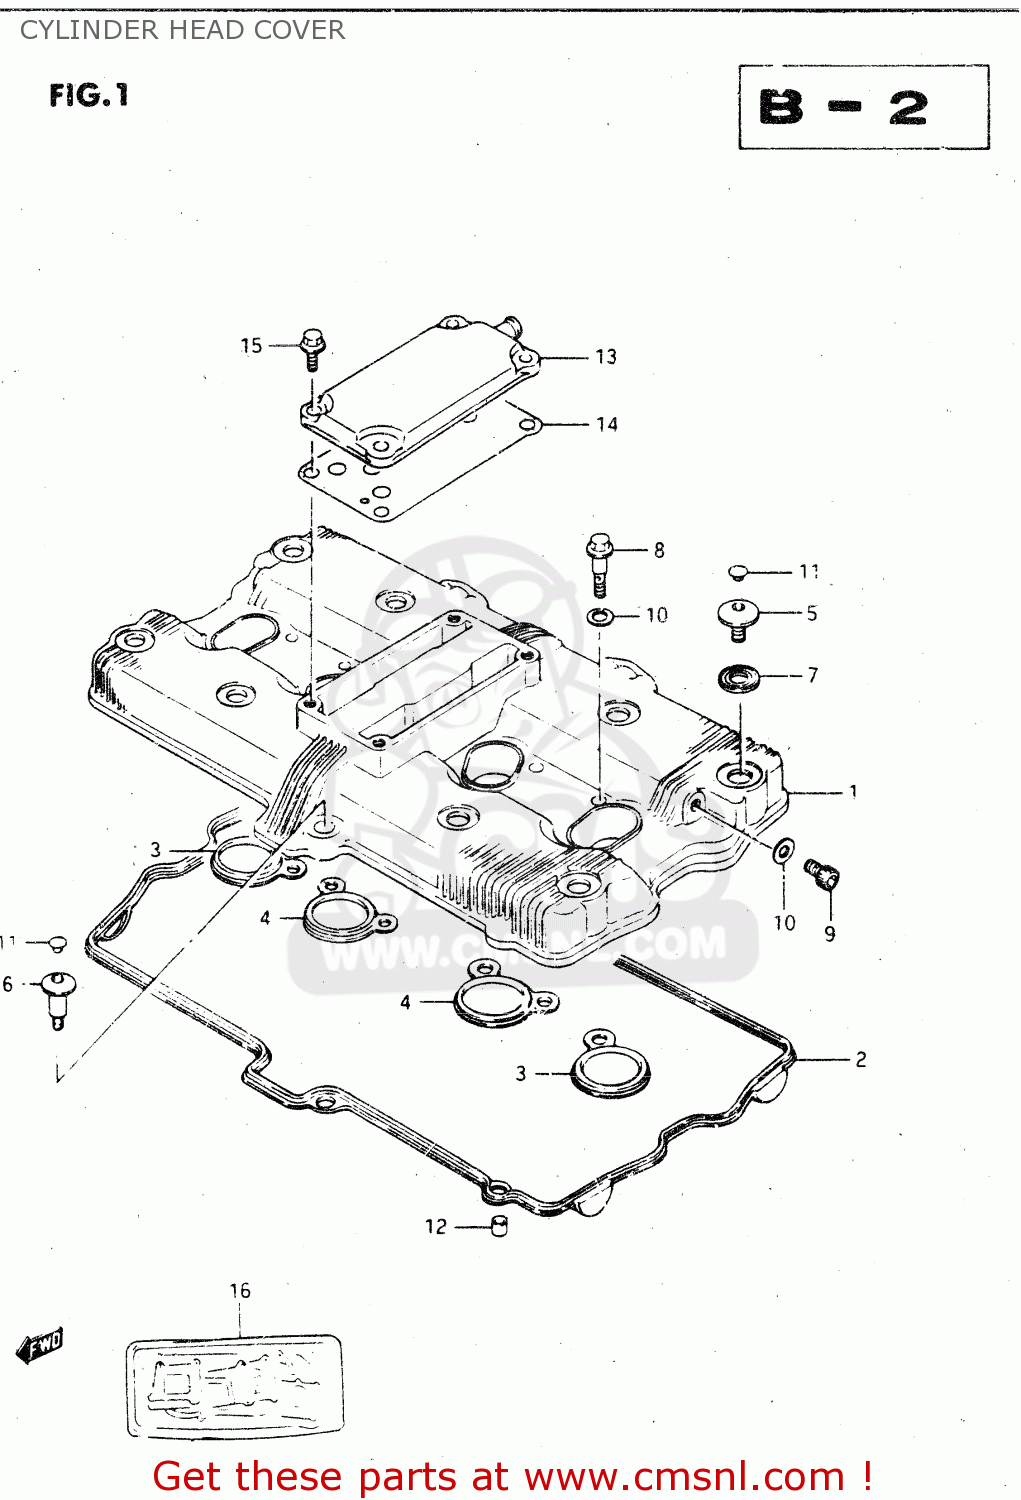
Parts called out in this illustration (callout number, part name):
1	COVER,CYLINDER HEAD
2	GASKET,CYLINDER HEAD COVER (NAS)
3	GASKET (NAS)
4	GASKET,HEAD COVER NO.3 (NAS)
5	BOLT(7X17.5)
6	BOLT(7X31)
7	WASHER
8	BOLT,UNION 8X35
9	PLUG, HEAD COVER
10	GASKET 8.2X14X1 (NAS)
11	CAP(OD:10)
12	PIN
13	COVER,BREATHER
14	GASKET (NAS)
15	BOLT
16	GASKET SET
